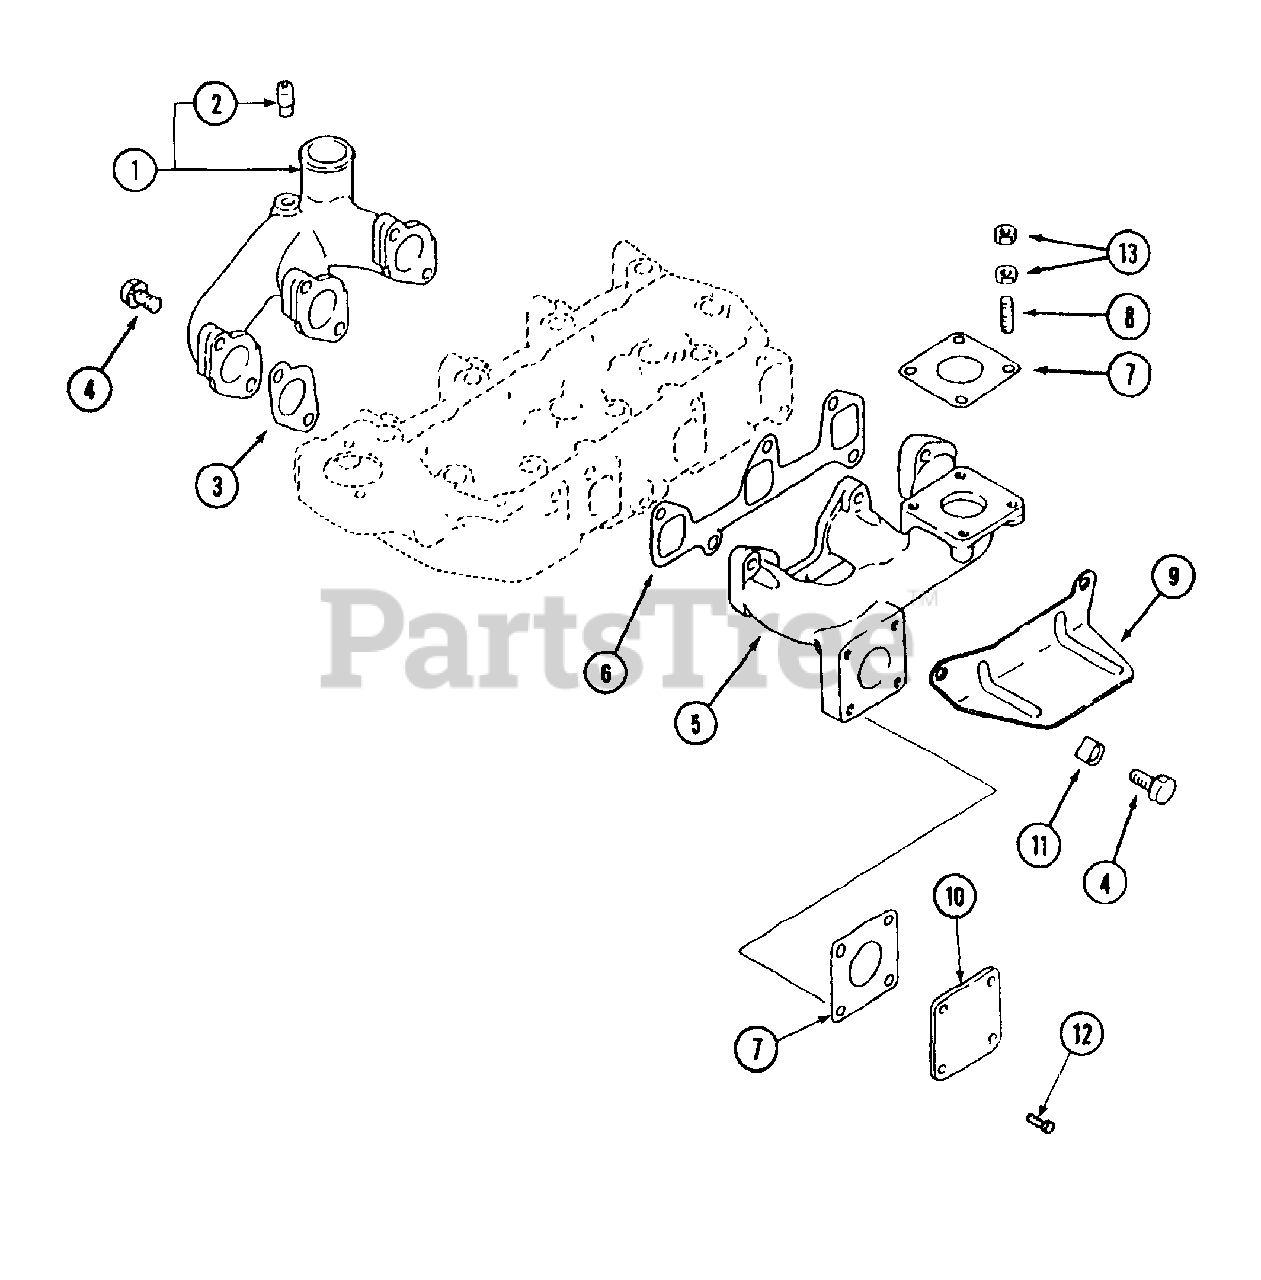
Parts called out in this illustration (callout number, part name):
1	Manifold Ass'y., Intake
2	Pipe
3	Gasket, Intake Manifold
4	Bolt
5	Manifold, Exhaust
6	Gasket, Exhaust Manifold
8	Stud
9	Cover, Starter
11	Clamp, Cable
12	Bolt
